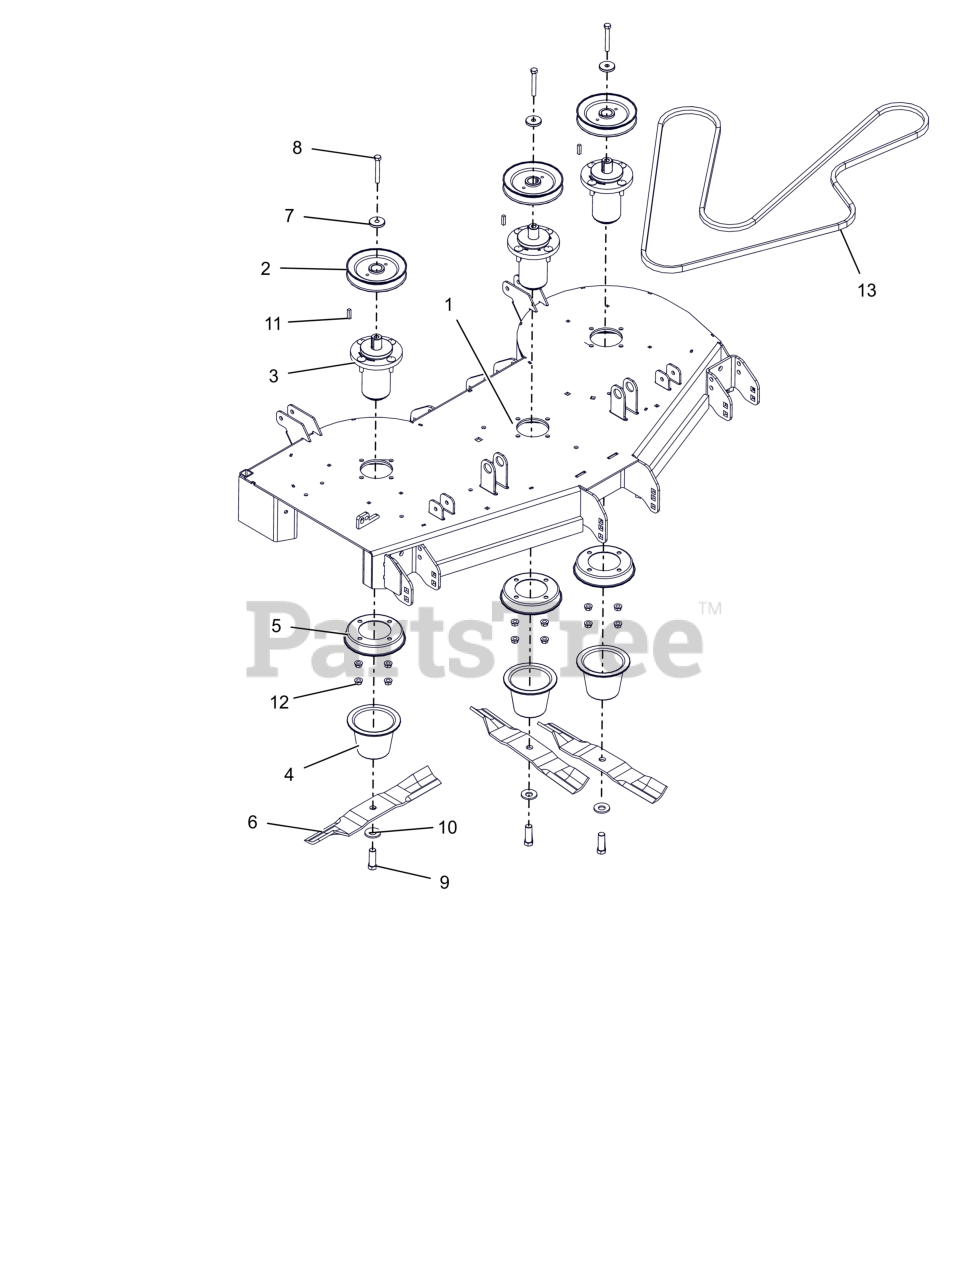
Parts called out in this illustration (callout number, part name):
1	WLDMT, 48" PROSTANCE DECK (RED)
2	PULLEY, V-1.00 ID X 5.75 OD (BLACK)
3	ASM, MAINT FREE ALUM SPINDLE
4	GUARD, SPINDLE LOWER
5	GUARD, SPINDLE TOP
6	BLADE, 16.19" MOWER (HI-LIFT)
7	RETAINER, SHEAVE
8	BLT, HEX .38-16X2.75 G8 ZCC
9	BLT, HEX .62-18X1.75 G8 ZCC
10	WSHR-BLVL .669X1.535X.138
11	KEY, SQ .25X.25X1.00 RC 40-50
12	NUT-LK-CTR-FLG .375-16 GF ZCC
13	BELT, B-SECTI0N EPDM RAW EDGE
